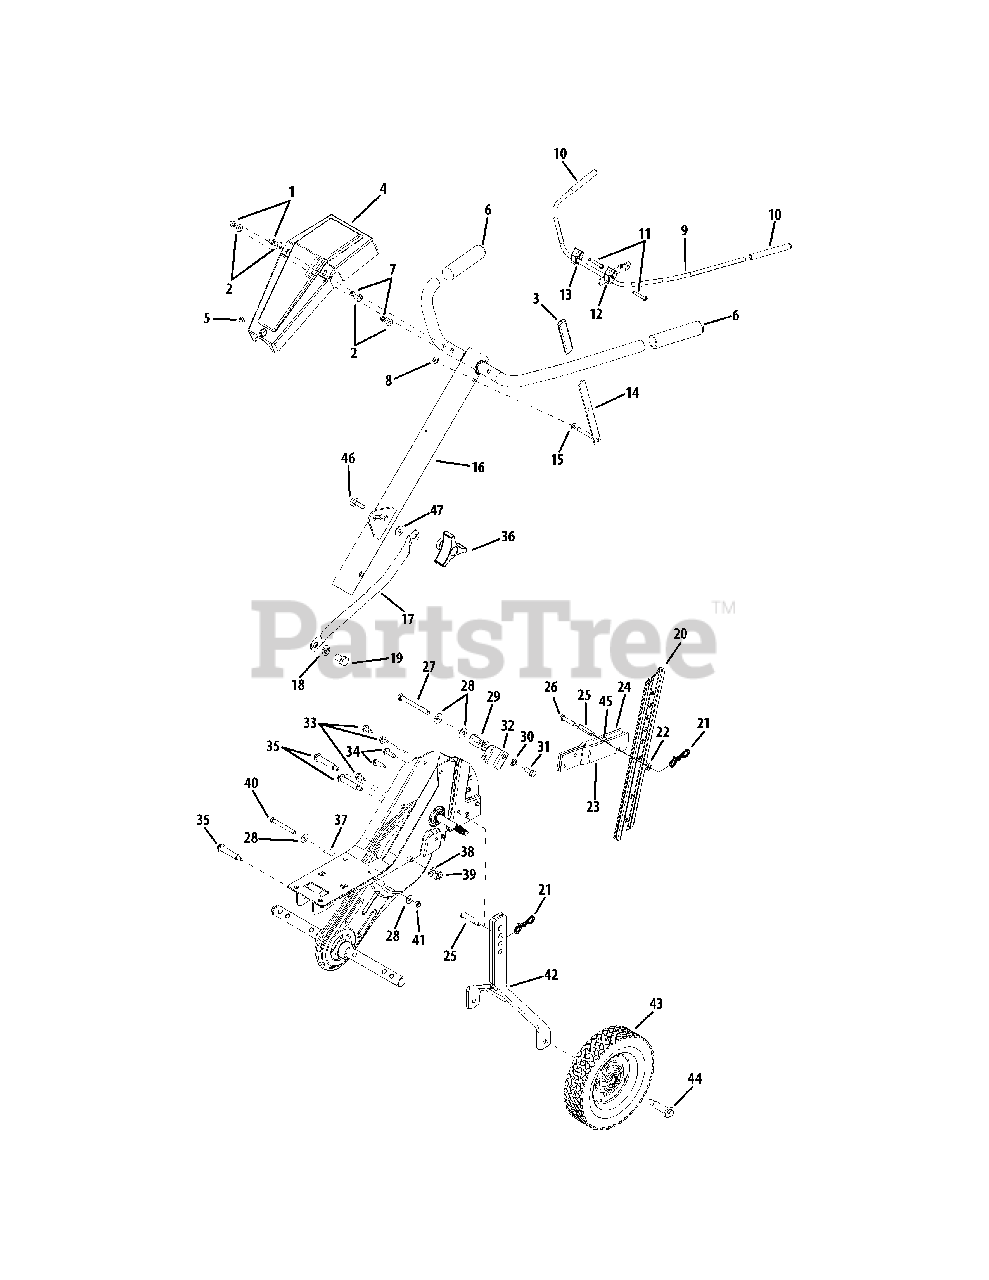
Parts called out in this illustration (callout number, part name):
1	Acorn Lock Nut, 1/4-20
2	Flat Washer, .271" x.630"
3	Reverse Handle Grip
4	Handle Cover w/o throttle (390)
4	Handle Cover (340)
5	Truss Machine Screw, #10 x 1/2"
6	Handle Grip
7	Hex Nut, 1/4-20 (390)
7	Jam Nut, 1/4-20 (340)
8	Cap Speed Nut
9	Clutch Handle Assembly
10	Clutch Grip
11	Hex Bolt, 1/4-20 x 2.25"
12	Clutch Handle Holder
13	Flat Washer, .385" x .62"
14	Reverse Handle Assembly
15	Flat Washer, .344" x .62"
16	Handle Assembly Complete
17	Handle Brace
18	Lock Washer, 1/2
19	Hex Bolt, 1/2-20
21	Cotter Pin, Bow Tie
22	Hex Flange L-Nut, 5/16-18
23	Tail Piece Bracket, Left
24	Tail Piece Bracket, Right
25	Clevis Pin
26	Hex Bolt, 5/16-18 x 1.5"
27	Hex Bolt, 5/16-18 x 3"
28	Bell Washer, .340" x .872"
30	L-Washer, 5/16"
31	Hex Bolt, 5/16-18
32	Cable Guide Bracket
33	Hex Washer Screw, 5/16-18 x .62"
34	Hex Washer TT-Tap Screw
35	Shoulder Bolt, 5/16-18
36	Hand Knob
38	Lock Washer, 7/16
39	Jam Nut, 7/16-20
40	Hex Bolt, 5/16-18 x 2.75"
41	Nylon Hex Nut, 5/16-18
42	Wheel Hanger Bracket Assembly
43	Wheel, 8 x 1.75
44	Shoulder Screw, .496 x 1.445
46	Carriage Bolt, 5/16-18 x 1
47	Bell Washer, .34"
